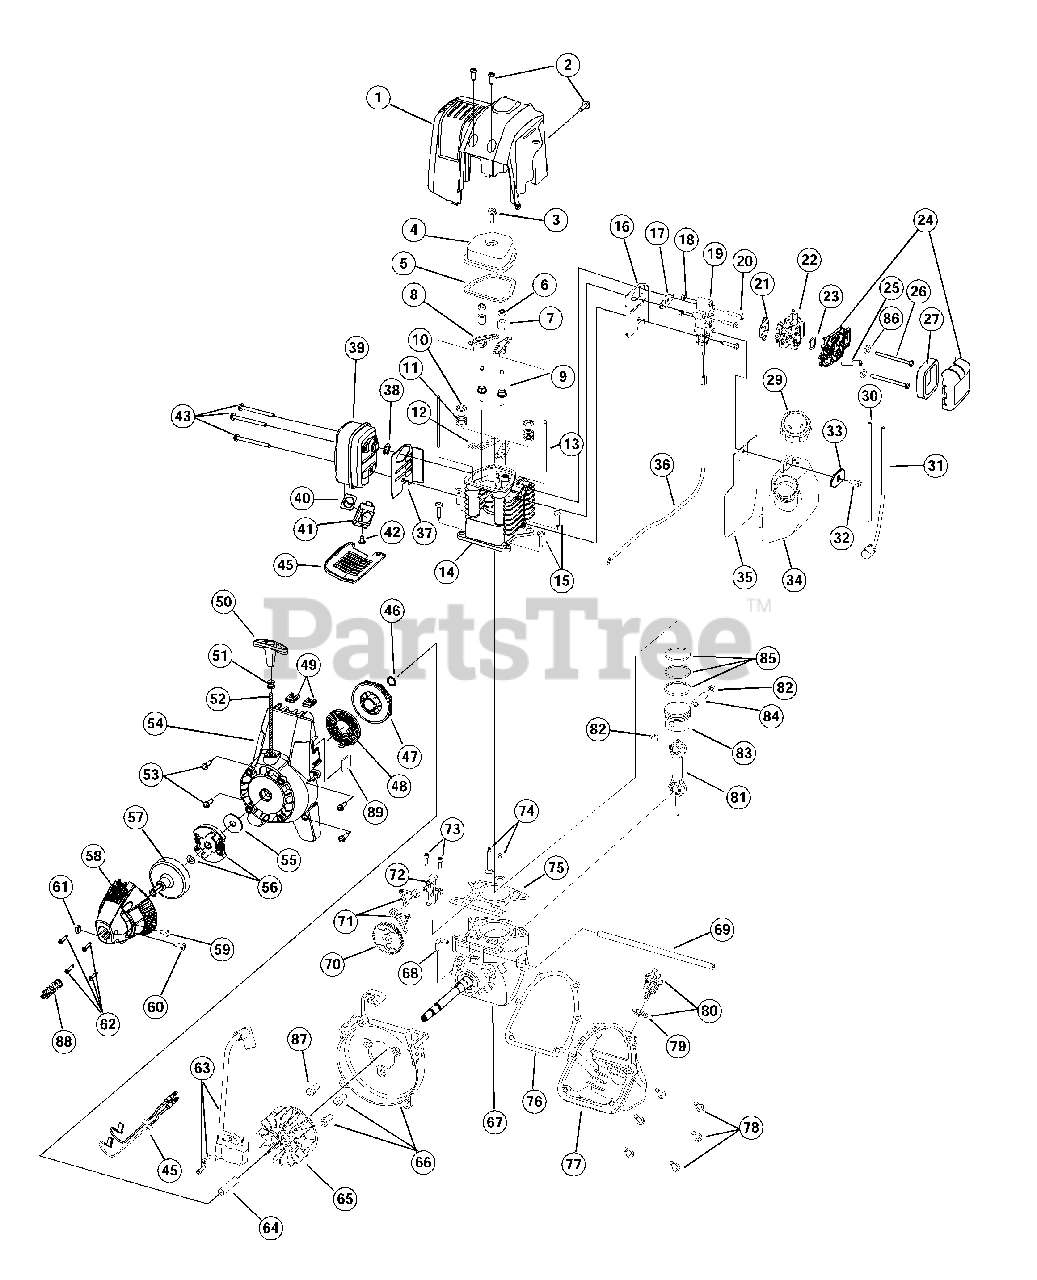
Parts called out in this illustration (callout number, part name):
1	Engine Cover
2	Engine Cover Screws
3	Valve Cover Screw
4	Valve Cover
5	Valve Cover Gasket
6	Rocker Adjustment Nut
7	Rocker Arm Pivot
9	Rocker Arm Stud
10	Valve Spring Retainer
11	Valve Spring
12	Push Rod Guide
13	Push Rod
14	Cylinder Head
15	Cylinder Screw
16	Intake Baffle
17	Carburetor Mount Gasket
18	Nut
19	Carburetor Mount
20	Carburetor Mount Screw
21	Carburetor Gasket
22	Carburetor with Primer
23	O-Ring, Carburetor
24	Air Filter/Choke Cover Assembly
25	Breather Tube
26	Air Filter Mounting Screw
28	Air Filter Cover
30	Fuel Return Line
31	Fuel Pick-Up Line with Filter
34	Fuel Tank Assembly
35	Fuel Tank Shield
36	Throttle Cable
37	Muffler Baffle
38	Muffler Gasket
39	Muffler
40	Spark Arrestor Screen
41	Screen Cover
42	Muffler Mounting Screw
44	Muffler Cover
45	Switch Wire Assembly
46	Palnut
47	Recoil Pulley
48	Recoil Spring
50	Pull Handle
53	Starter Housing Screw
54	Starter Housing Assembly
55	Clutch Washer
56	Clutch with Spacer
57	Clutch Drum
58	Clutch Cover
59	Anti-Rotation Screw
60	Screw
62	Clutch Cover Screws
63	Ignition Module with Screws
65	Flywheel
66	Shroud Assembly with Screws
67	Crankcase Assembly
69	Breather Hose
71	Cam Follower Set
72	Cam Bracket
73	Cam Bracket Screw
74	Valves, Intake and Exhaust
75	Cylinder Gasket
76	Oil Pan Gasket
77	Oil Pan
78	Oil Pan Screw
79	Dipstick Assembly
81	Connecting Rod
82	Wrist Pin Button
83	Piston
85	Piston Ring Set
88	Compression Spring
